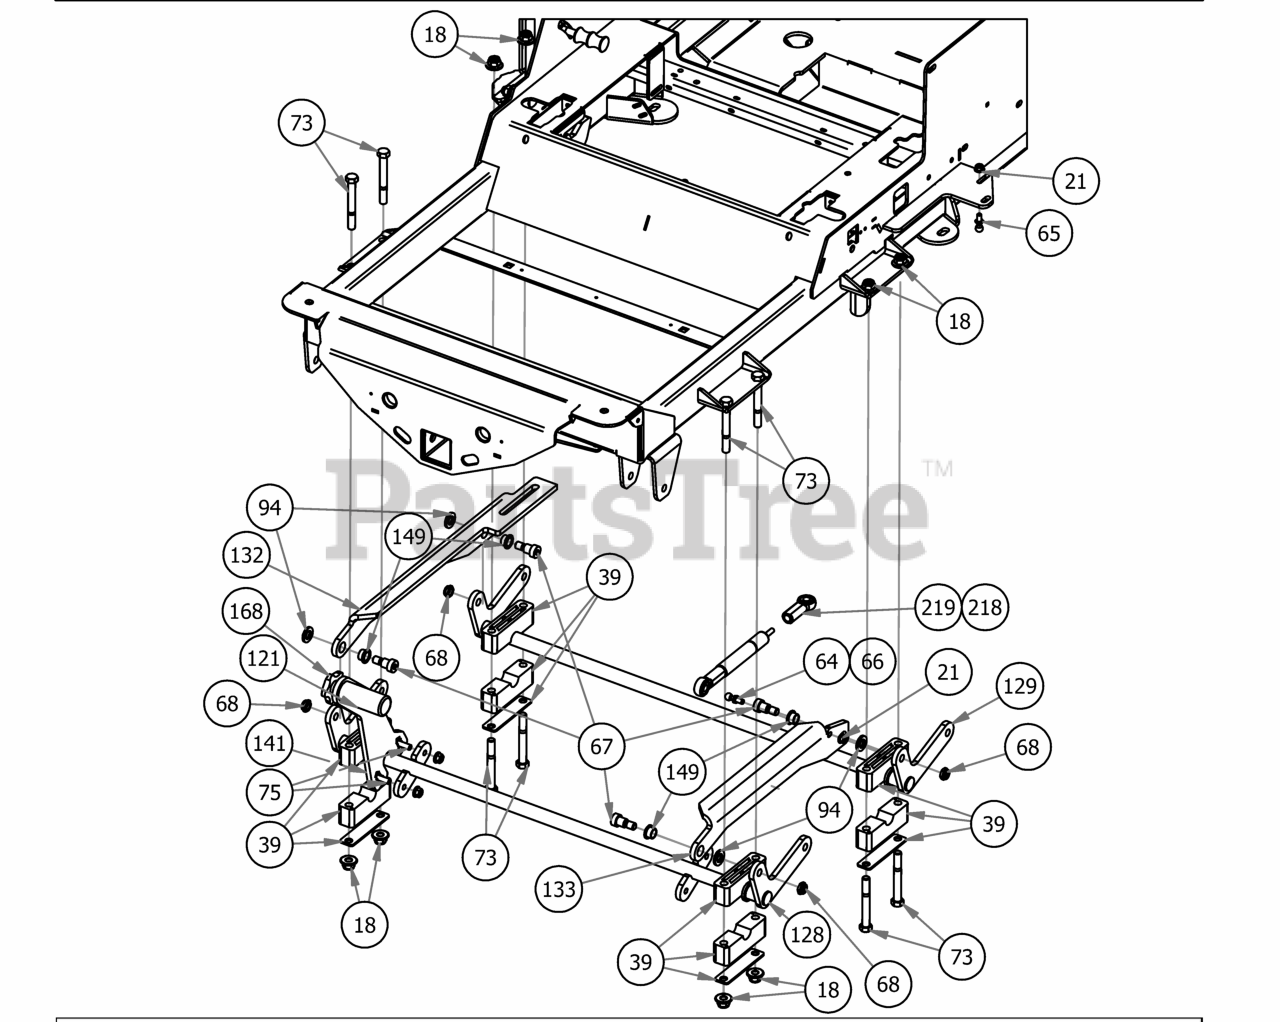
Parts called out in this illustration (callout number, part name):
9	3/8-16 NYLON INSERT FLANGE LOCKNUT (GR.F) ZINC
18	1/2-13 NYLON INSERT FLANGE LOCKNUT ZINC
21	5/16" Flange Nut
39	Pillow Block Assembly
64	13mm Damper Ball Stud-Steering
65	10mm Damper Ball Stud-Steering
66	10mm Damper Ball Stud-XP Linkage
67	5/8'' x 5/8'' Shoulder Bolt
68	1/2" Nylcock Nut (1/2 Jam)
73	1/2" x 4" Bolt (Grade 8)
75	3/8" x 1 1/4" Carriage Bolt
94	.635 ID X 1.120 OD X .140 THICK FLAT WASHER NYLON
121	Knurled Pedal
128	2019 Outlaw Actuator - Front
129	2019 Outlaw Actuator - Rear
132	2019 Actuator Linkage - Right
133	2019 Actuator Linkage - Left
141	Foot Lift Upright Lever
149	Bronze Bushing - SF - 2024-8
168	Foot Pedal Knob 1/2-13
203	2019 Horizontal Gas Frame
218	250lb Gas Spring - 61" Deck
219	300lb Gas Spring - 72" Deck
